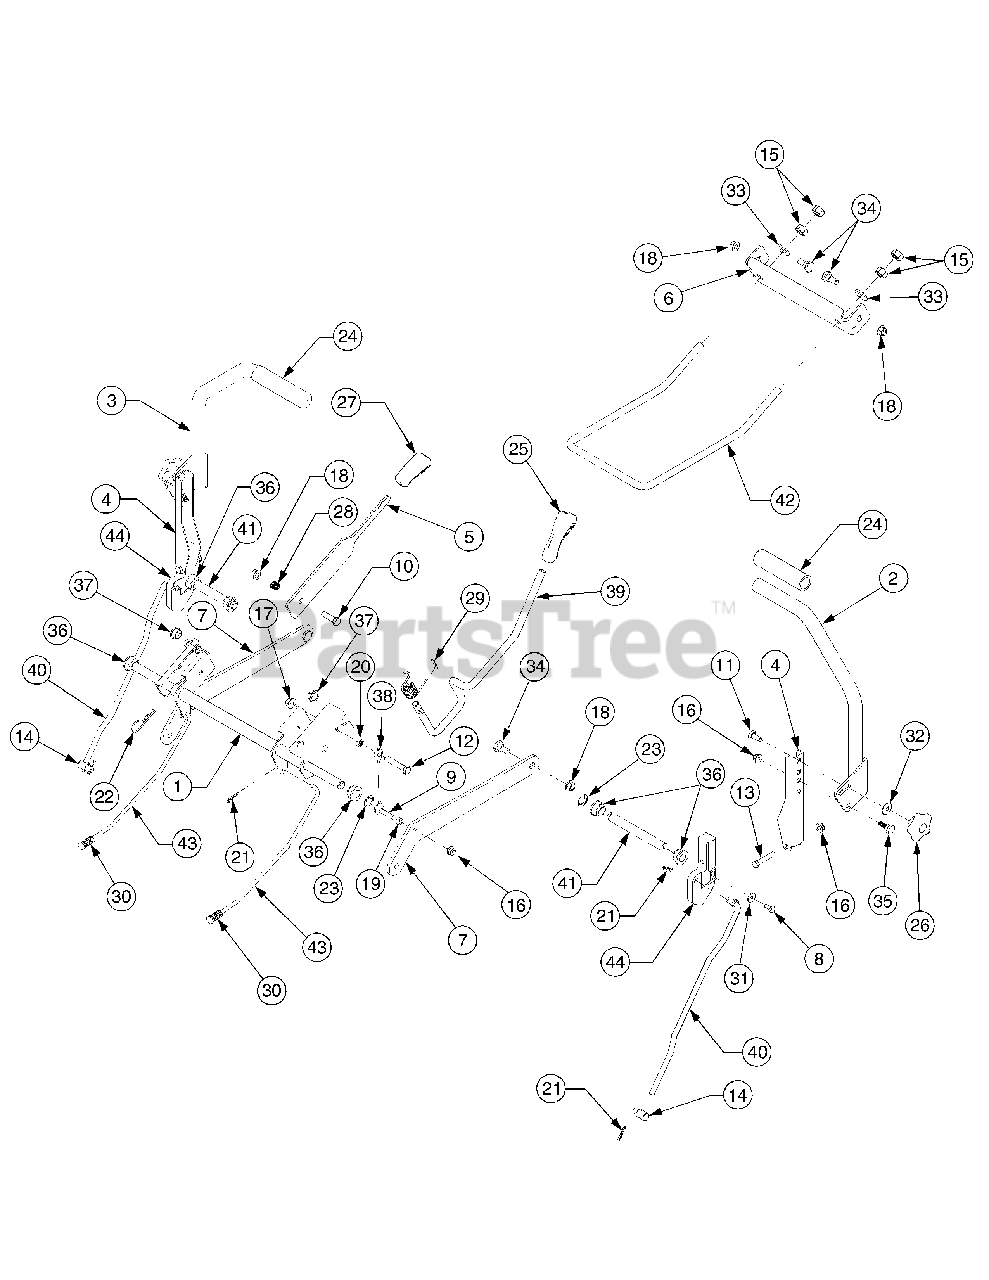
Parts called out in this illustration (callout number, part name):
1	Shaft Assembly, Deck Lift
4	Bracket, Lapbar Pivot
8	Screw, Hex Lock, 1/4-20 x .62 GR5
9	Screw, Hex Cap, 5/16-18 x 1.5 GR5
10	Screw, Hex Cap, 3/8-16 x 1.25 GR5
11	Bolt, Carriage, 5/16-18 x .875 (If equipped)
12	Screw, Hex Cap, 3/8-16 x 2.0 GR5
13	Screw, Hex Cap, 5/16-18 x 1.75 GR5
14	Ferrule, 3/8-24 x .375
15	Nut, Hex Jam, 1/2-13 GR5
16	Nut, Hx Flange Insert Lck, 5/16-18 GrF
17	Nut, Hx Flange Insert Lck, 3/8-16GrF
18	Nut, Hex Flange Lock, 3/8-16 GRF
19	Nut, Hex Jam, 5/16-18 GR5
20	Nut, Hex Jam, 3/8-16 GR5
21	Pin, Internal Cotter
22	Pin, Internal Cotter
23	E-Ring , .625 Dia. Shaft
25	Grip, Handle
26	Knob, Nut, 5/16-18 Nylon Lock (If equipped)
28	Spring, Compression
29	Spring, Torsion
30	Spring, Compression
31	Washer, Bell, .265 x .75 x .062
32	Washer, Bell, .325 x .93 x .045
33	Washer, Flat, .531 x 1.062 x .134 HT
34	Screw, Shoulder, .498 x .340:3/8-16
35	Screw, Shoulder, .437 x .268:5/16-18
36	Bearing, Hex Flange
37	Bearing, Flange, .626 x .938 x .344
38	Cable, Deck Lift, 5.05 Long
39	Rod, Deck Lift Handle
40	Rod, Lapbar Control
41	Shaft, Control
42	Rod, Deck Front Hanger
43	Rod, Brake
